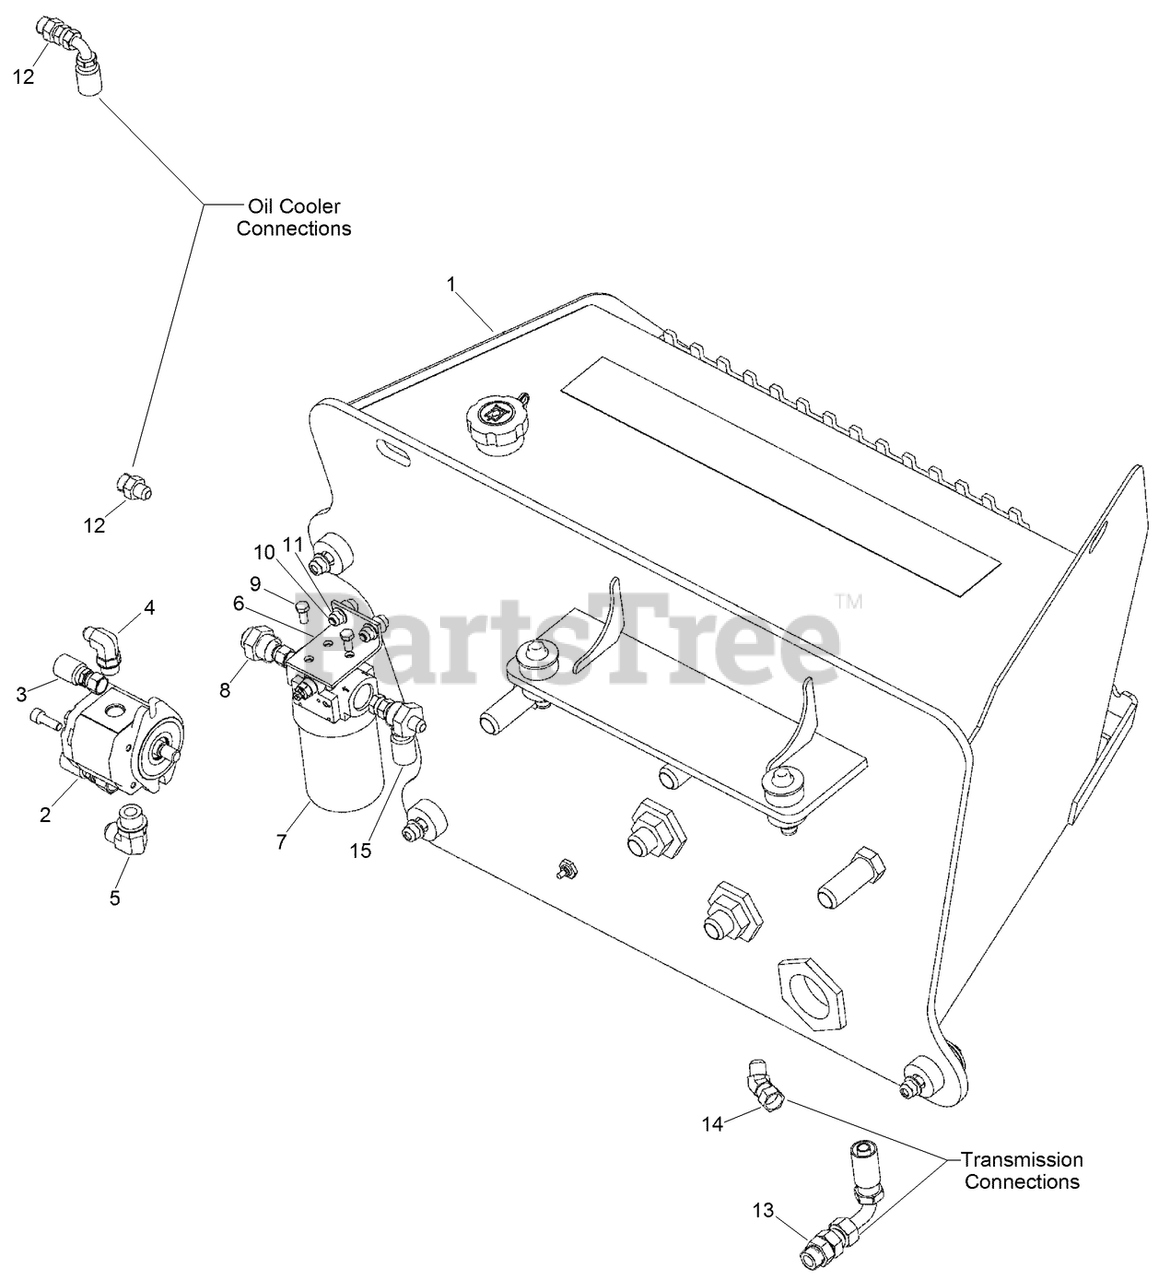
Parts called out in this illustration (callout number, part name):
1	HYD TANK ASM
2	GEAR PUMP ASM
3	SCREW-HSH
4	ELBOW-90 Deg, 1/2 to 5/8
5	ELBOW-90 Adj 37FL 3/4 Tube
6	BRACKET-MOUNTING, FILTER
7	OIL FILTER ASM
8	CONNECTOR ASM
9	SCREW-HH
10	SCREW-HH
11	NUT-FLANGE, NYLOCK
12	CONNECTOR - Str Thd 1/2, 37FL-ORB 5/8
13	FITTING-STRAIGHT
14	ELBOW - 45 Swivel, 37FL 5/8 Tube
15	KIT, Hydraulic Hoses
